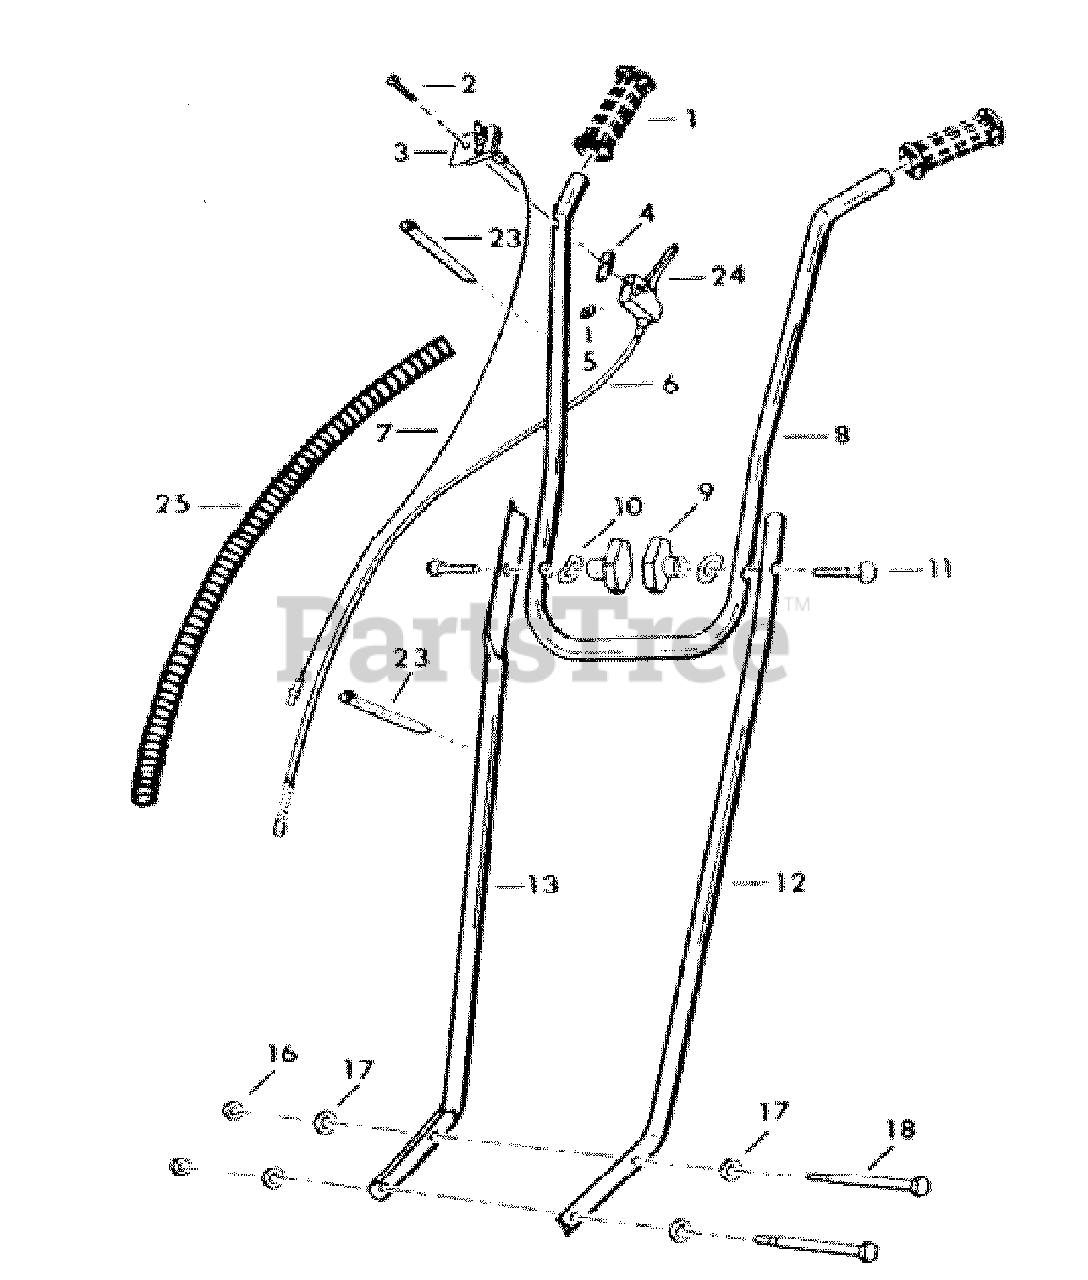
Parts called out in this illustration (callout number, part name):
1	Grip, Handlebar
2	Screw, #10-24 x 1 3/8
3	Switch Assy, w/Mtg Plate
5	Nut, Throttle/Switch Assy
6	Throttle Cable
7	Wire Assembly
8	Handlebar, Upper
9	Knob, Plastic, Handlebar
10	Washer, Curved Knob
11	Screw, Curved Hd 5/16-18 x 1 1/2
12	Handlebar, Lower L.H.
13	Handlebar, Lower R.H.
16	Nut, 1/4-20
17	Washer, Curved
18	Screw, 1/4-20 x 4 1/2
24	Throttle Trigger
25	Housing, Wire Assy & Thrl Cable
